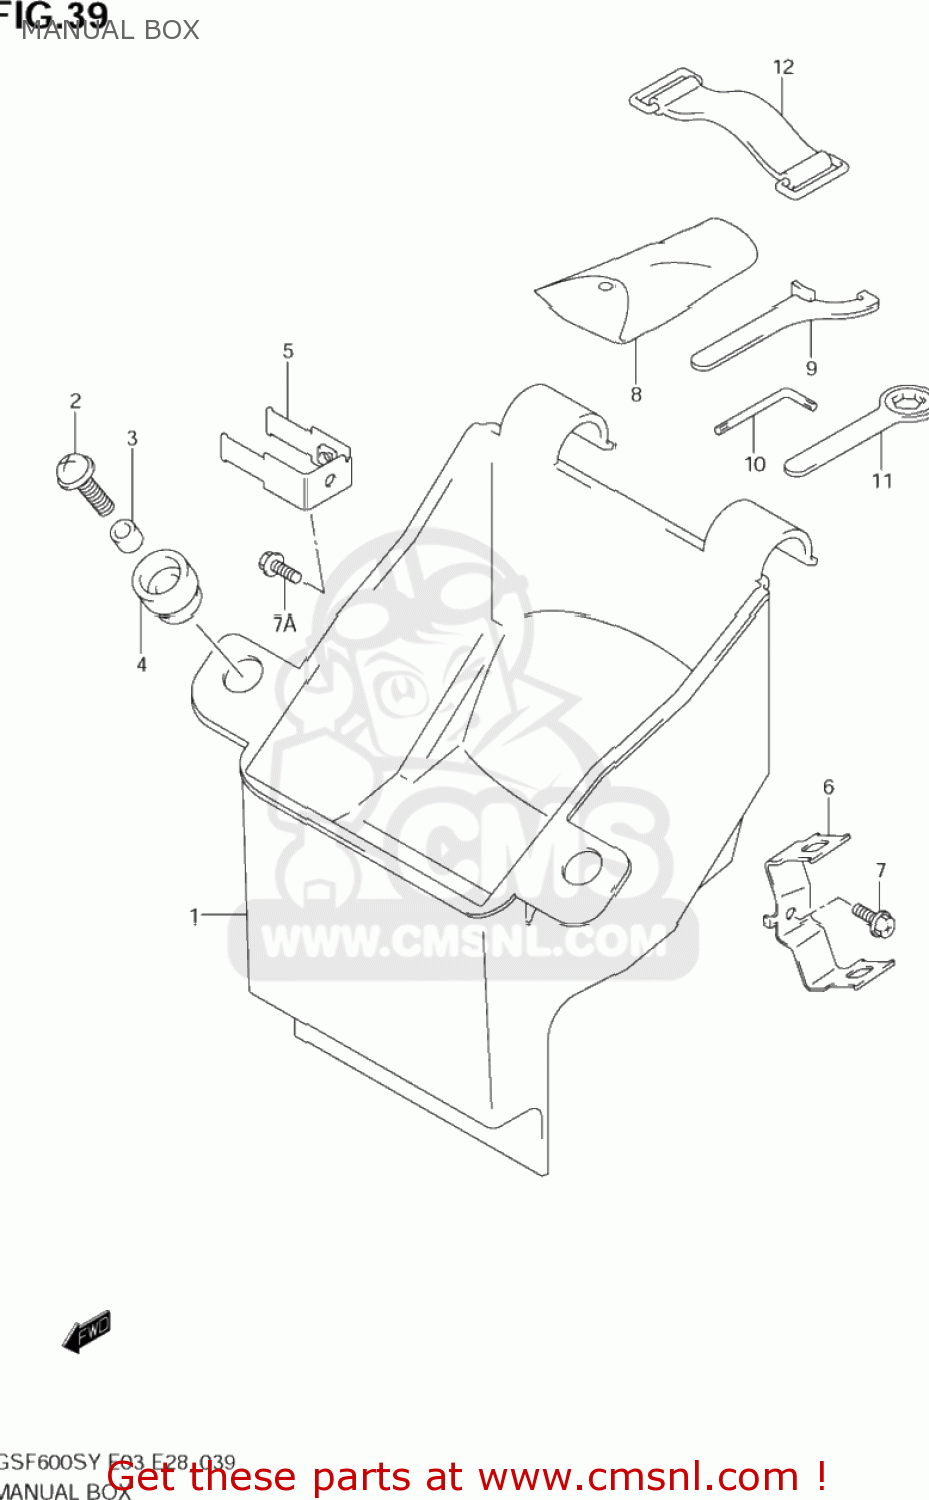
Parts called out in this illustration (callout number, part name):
1	BOX,MANUAL
2	SCREW(6X20)
3	SPACER(6.5X10X8)
4	CUSHION
5	PLATE,RLY FITING
6	PLATE,IGNITOR FITING
7	BOLT
7A	BOLT
8	TOOL ASSY
9	CLAMP
10	HEXAGON SPANNER,5
11	RING SPANNER(22)
12	BAND
